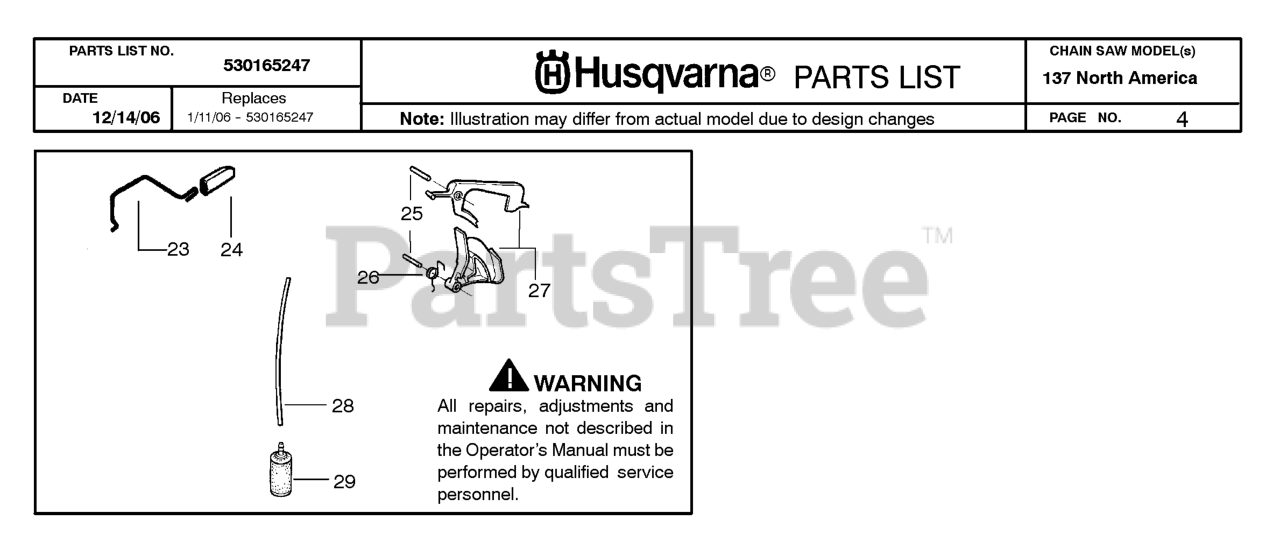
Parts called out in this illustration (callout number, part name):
23	THROTTLE SHAFT 36/41
24	THROTTLE ACTUATOR 36/41
25	PIN,TRIGGER 36/41
26	TRIGGER SPRING 36/41
27	THROTTLE TRIGGER-KIT
28	HOSE. FUEL
29	FUEL PICK-UP
